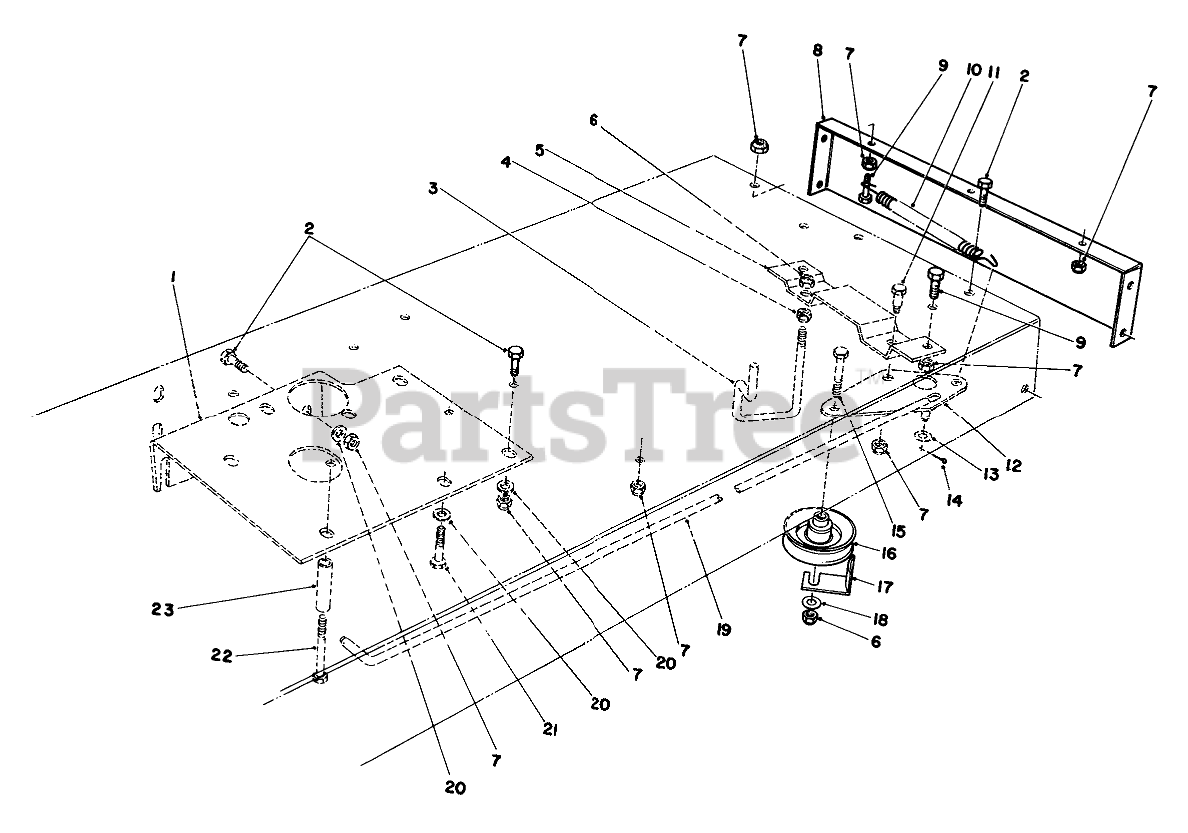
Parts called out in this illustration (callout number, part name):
1	REINF PLATE R
2	SCREW-HH
3	BELT GUIDE
4	NUT-LOCK, SIDE
5	TRACT SUPP BRKT B
6	NUT-LOCK, CONE
7	NUT-LOCK, NI
8	REAR FRAME R
9	SCREW-HH
10	TRACTION SPRING
11	BOLT-SHOULDER
12	TRACTION PIVOT BRKT
13	WASHER-FLAT
14	PIN-COTTER
15	SCREW-HH
16	PULLEY-IDLER
17	RETAINER-BELT
18	WASHER-FLAT
19	TRACTION ROD
20	WASHER-PLAIN
21	Screw-HH
22	SCREW-HH
23	OUTER TUBE SPACER
